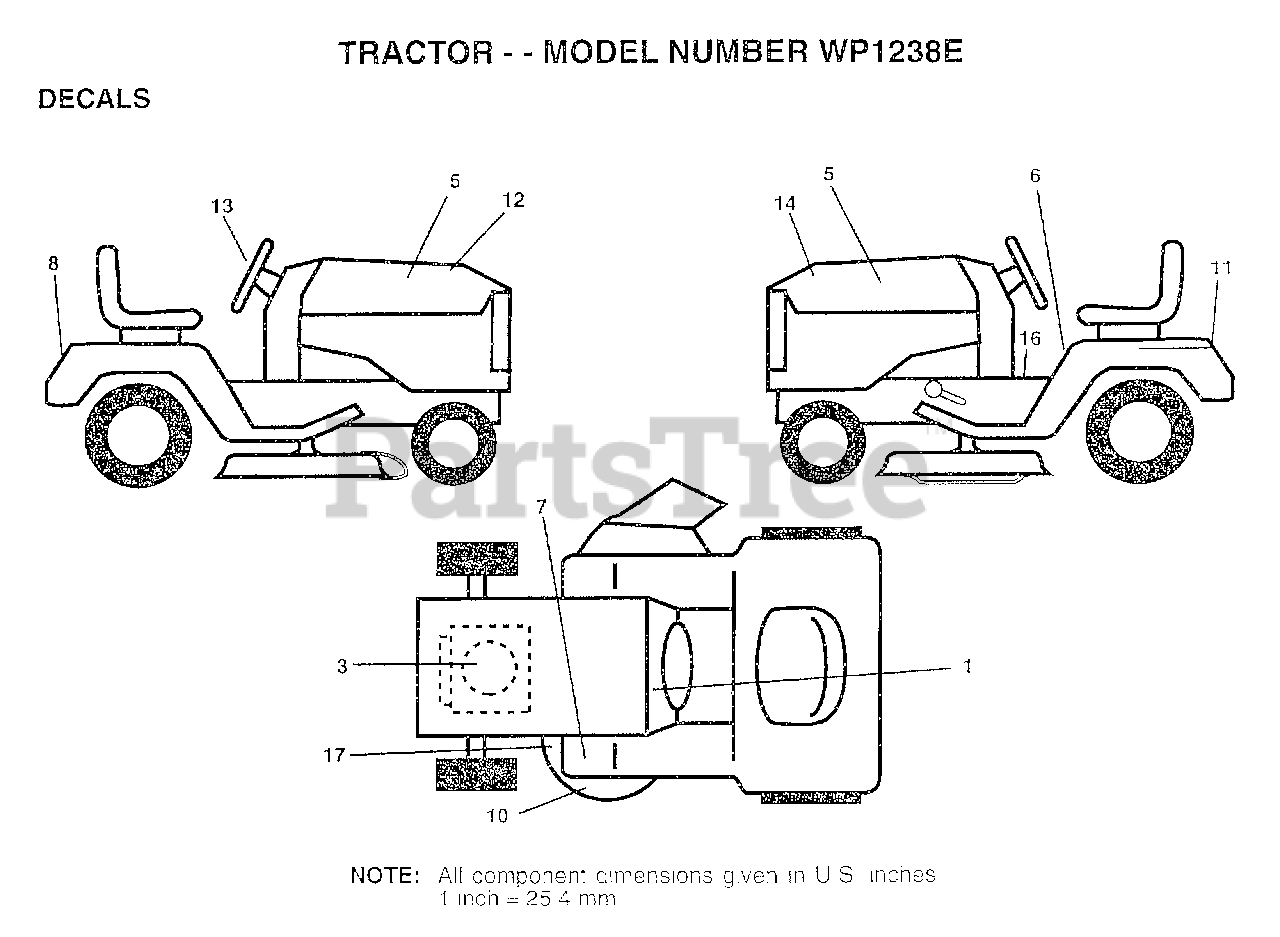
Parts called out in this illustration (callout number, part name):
1	"DECAL-OPER,GEAR D"
3	DECAL, HP ENGINE
5	DECAL.HOOD.LOGO.
6	"DECAL DANGER,FEND"
8	DECAL, FENDER LOGO
11	DECAL.BATRY.3-3908
12	DECAL.HD.RH.WINST
13	DECAL, WHEEL CAP
14	DECAL.HD.LH.WINST
16	DECAL BRAK PARK
17	DECAL
